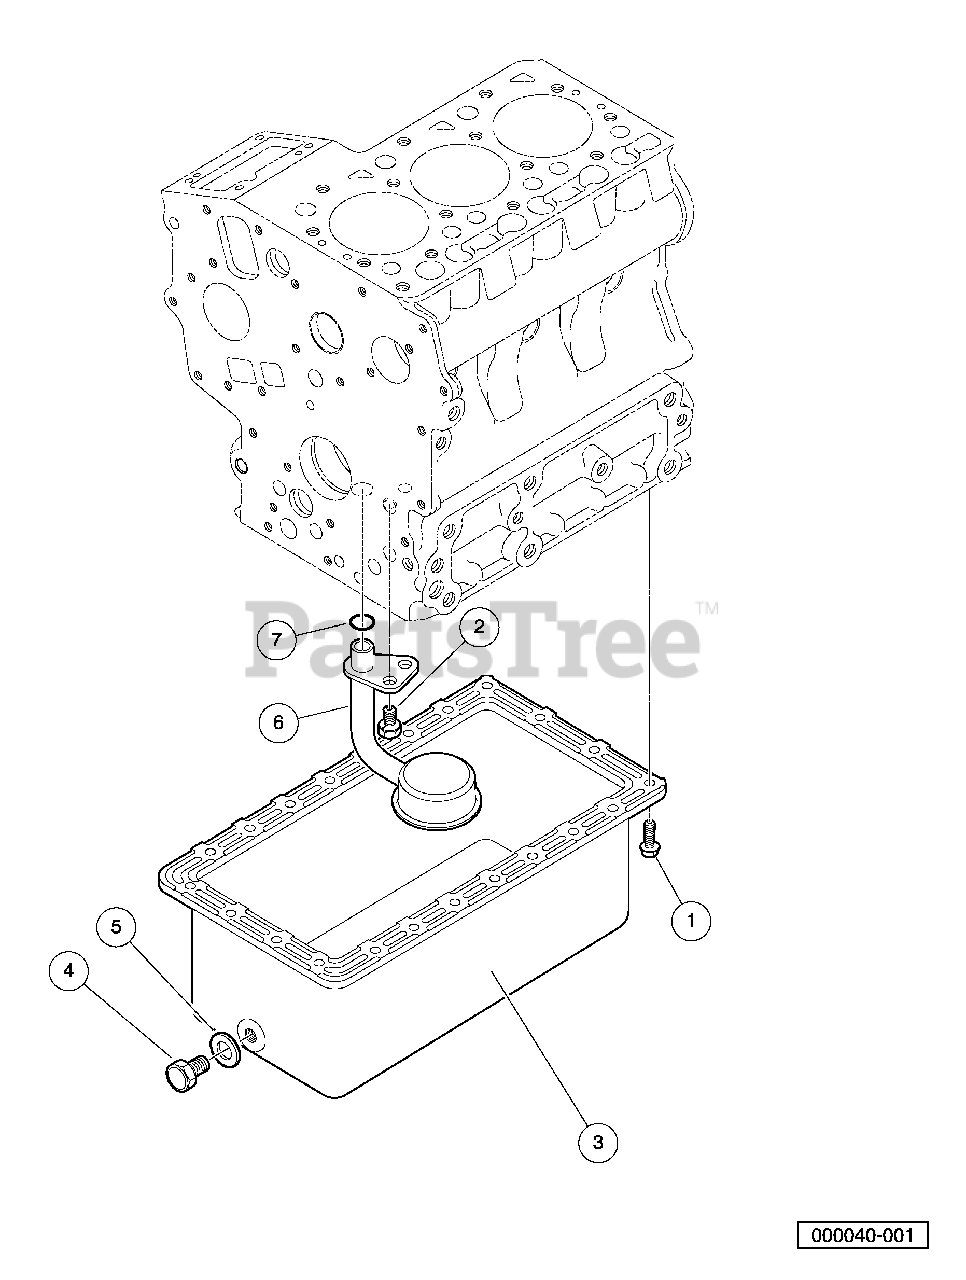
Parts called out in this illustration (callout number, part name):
1	Bolt, M6 X 1 X 14
2	Bolt, M8 X 1.25 X 15
4	Plug, Drain, M12 X 14
5	Gasket, 20 X 13
6	Filter, Oil, Pick Up
7	O Ring, 20 X 17
